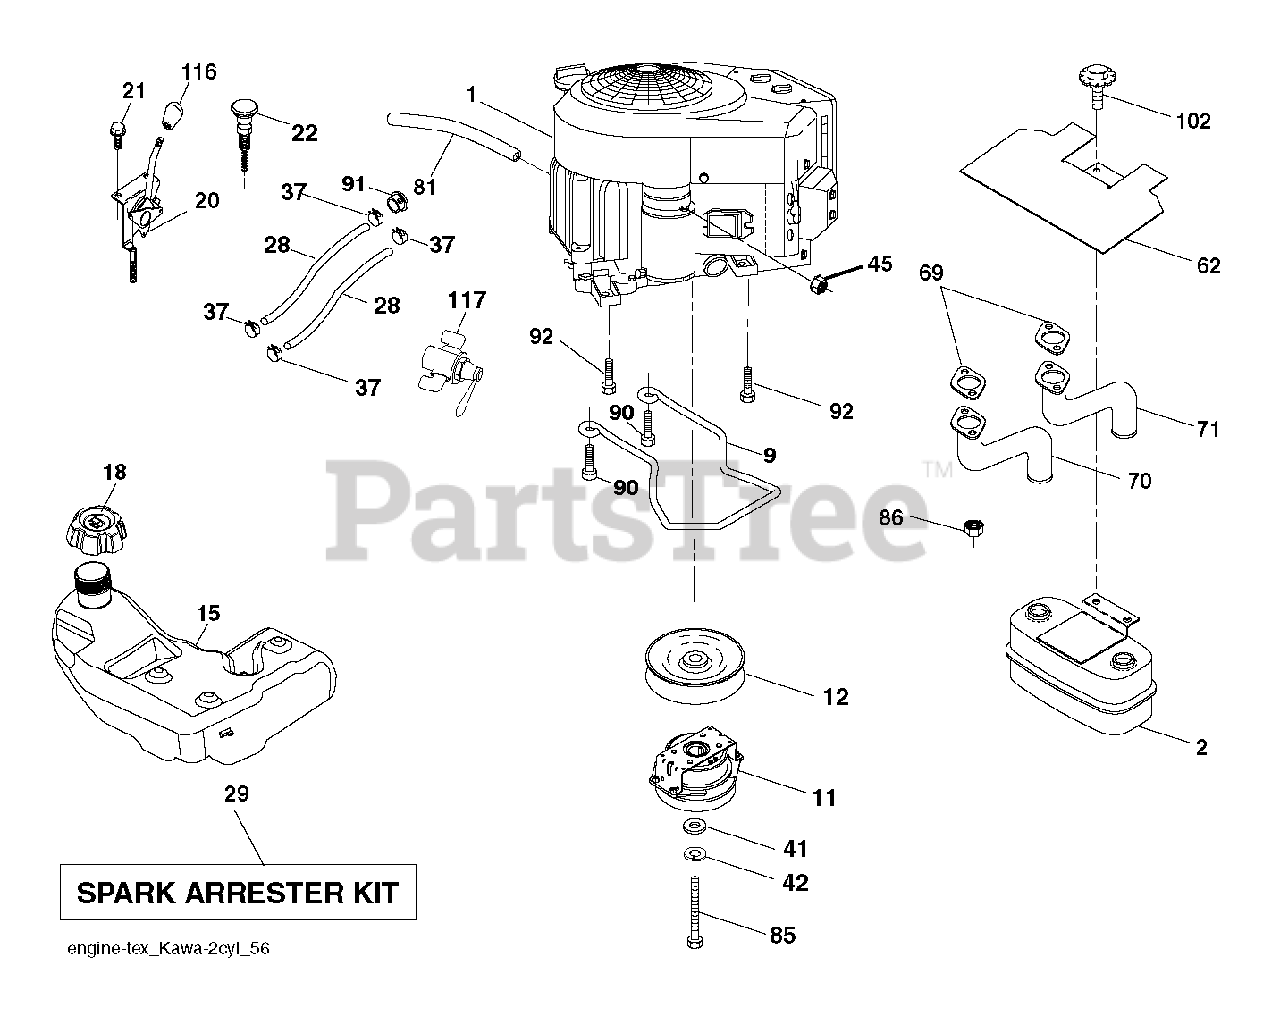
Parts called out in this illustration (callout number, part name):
2	MUFFLER.ASM.TWN.EXTNDED.DFLCTR
9	KEEPER.BELT.ENG.4.25"2.BLT.431
11	CLUTCH.OGURA.5.0PD.GT1.5A-EH01
12	PULLEY ENGINE
15	TANK.ASM.FUEL.4R.GAL.EPA.17
18	CAP ASSY FUEL 3" GRAY
20	CONTROL.THROTTLE.PRO.
21	SCREW.#10 X 0.750.BOS
22	CONTROL.CHOKE.ERGO.PUSH-IN.BLA
28	LINE.FUEL.64"REAR.EMIS
29	KIT.SPARK ARRESTOR 794945 B&S
37	HOSE CLAMP
42	LOCKWASHER
45	NUT
62	SHIELD.HEAT.MUFFLER
70	TUBE.EXHAUST.LH.FR961/FR730
71	TUBE.EXHAUST.RH.FR961/FR730
81	TUBE, DRAIN OIL ASM.
85	BOLT.HEX.7/16-20X3.GR5.YELLOW
86	NUT.HEX.FLANGE.TOPLOCK
90	SCREW 3/8-16X1
91	BUSHING.1.375OD
92	SCREW 3/8-16X1
102	SCREW
116	RP KNOB SOFT TOUCH
117	VALVE FUEL RESERVE
